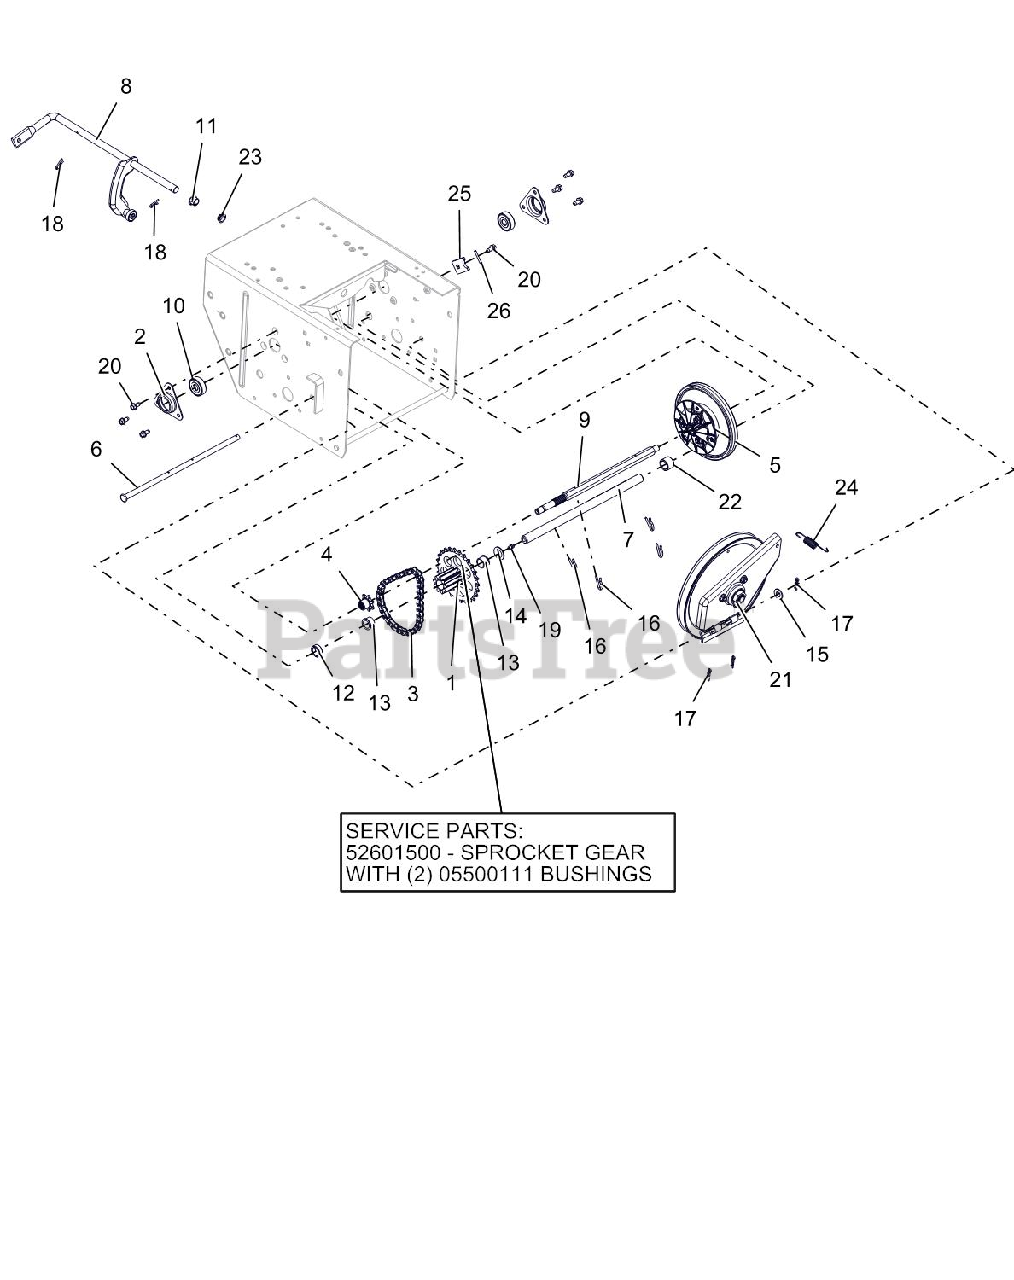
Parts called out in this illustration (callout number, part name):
1	BSHG-FLG .625X.750X.500X.875
1	PINION & SPROCKET
1	PINION & SPROCKET W/BUSHINGS
2	FLANGE, BEARING
3	CHAIN - #41, 32 PITCHES
4	SPROCKET, PINION 7T W/SPLINE
5	DISC, FRICTION DRIVE-ASSEMBLY
6	PIN, PIVOT
7	SHAFT, PINION - HARDENED
8	ARM, SHIFT-PRO (ASSEMBLY)
9	SHAFT, HEX - HEAT TREATED
10	BRG-BALL .437X1.375X.437
11	BUSHING, POLYLINER-.50 SPLIT
12	BSHG-SLV, .635X.880X.305
13	BSHG-FLG .625X.750X.500X.875
14	WSHR-FL-STL .630X1.005X.062 YZ
15	@WSHR-FL-STL.406X.812X.065 YWZ
16	PIN, SPRING CLIP
17	PIN-HAIR, ENDRIES #25 YWZC
18	CLIP, SPRING
19	ZERK,FITTING .25X.125 DRIVE IN
20	SCR-TAP .25-20X.50 HWH TR YWZ
21	PLATE, SWING ASSEMBLY-DEEP
22	SPACER, .635X.880X.611
23	BUSHING, POLYLINER-.50 SNAPIN
24	SG-TENS .048X.50X2.8
25	TAB, ANTI ROTATION
26	PIN-ROLL .125X1.00
